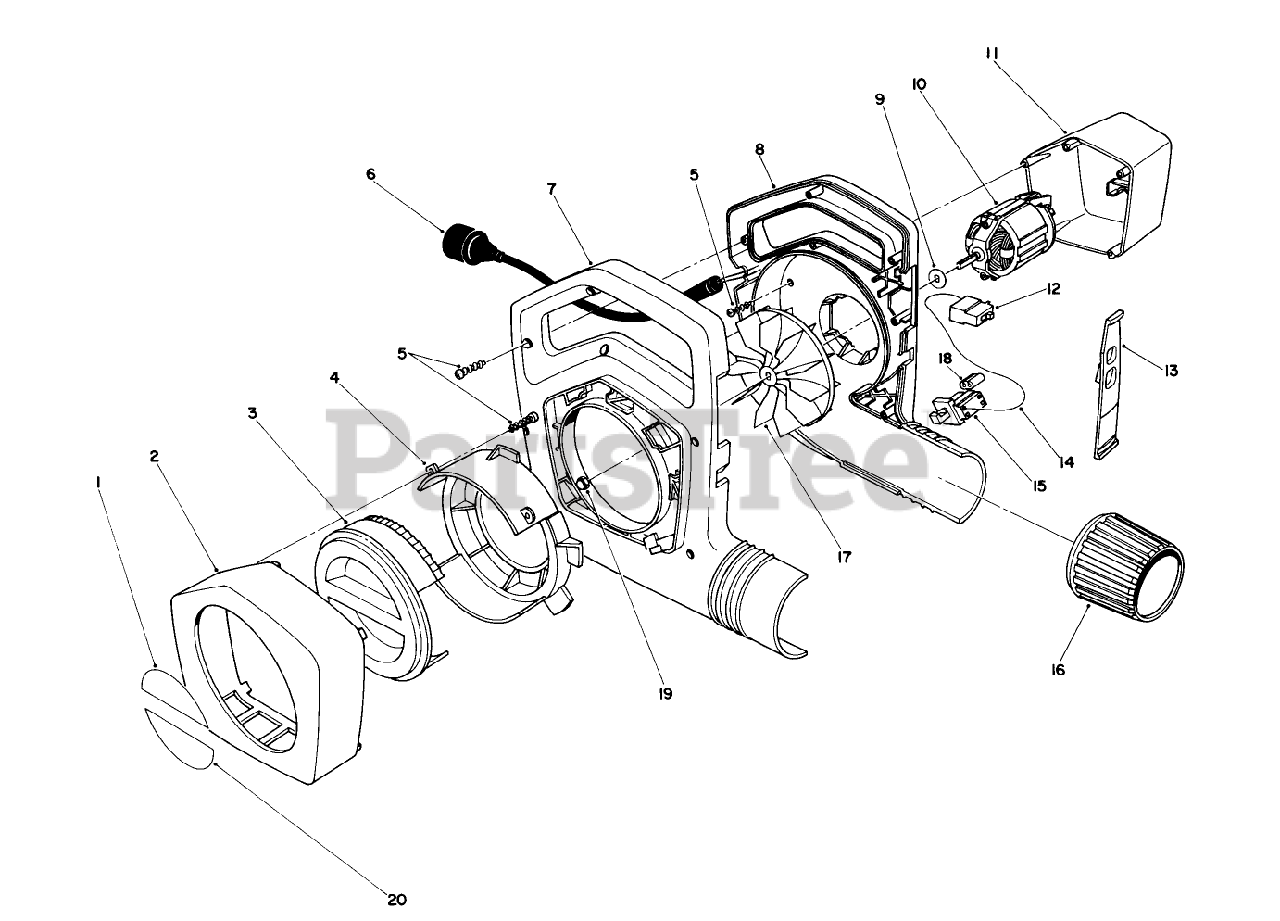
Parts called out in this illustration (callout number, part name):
13	Cam-Switch-On/Off (Model No. 51535C)
15	SWITCH-INTERLOCK
19	NUT-ACORN
